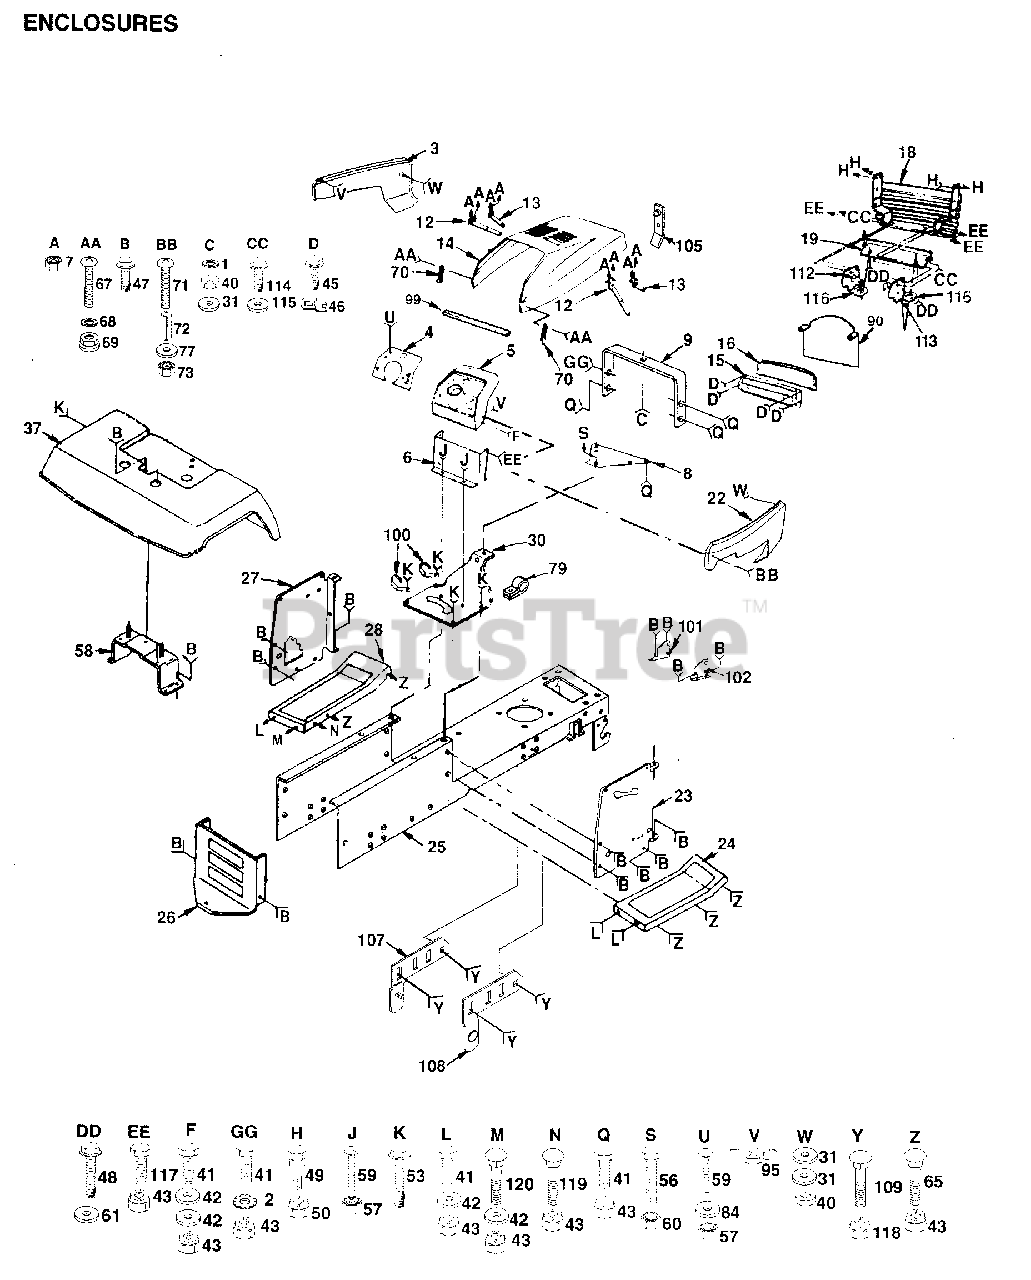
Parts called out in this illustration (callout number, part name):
1	LOCKWASHER
2	LOCKWASHER
3	"PANEL,SIDE LH "
7	NUT
9	SUPPORT ASS'Y
16	LENS LT
22	"PANEL,SIDE RH"
27	DASH PANEL LH
30	SADDLE. 6SP
31	WASHER PM
42	WASHER
46	"""J"" FASTENER LT"
47	SCREW
48	SCREW
53	SCREW LT
56	BOLT
58	BRKT FENDER
59	SCREW
61	WASHER
65	BOLT
67	SCREW
68	LOCKWASHER
69	WELDNUT
70	HOOD LATCH T
71	SCREW
72	SPACER LT
77	WASHER
79	CLIP T
84	WASHER
90	"BAFFLE,VERTICLE"
99	FOAM STRIP T
100	"CLIP,INSULATOR"
101	SUPPORT LH YTH
102	SUPPORT RH YTH
107	PIVOT BRKT LH
108	PIVOT BRKT RH
112	SUPPORT LH YTH
113	SUPPORT RH YTH
114	SCREW HEX CRT
115	WASHER
116	WASHER
117	BOLT
118	NUT
